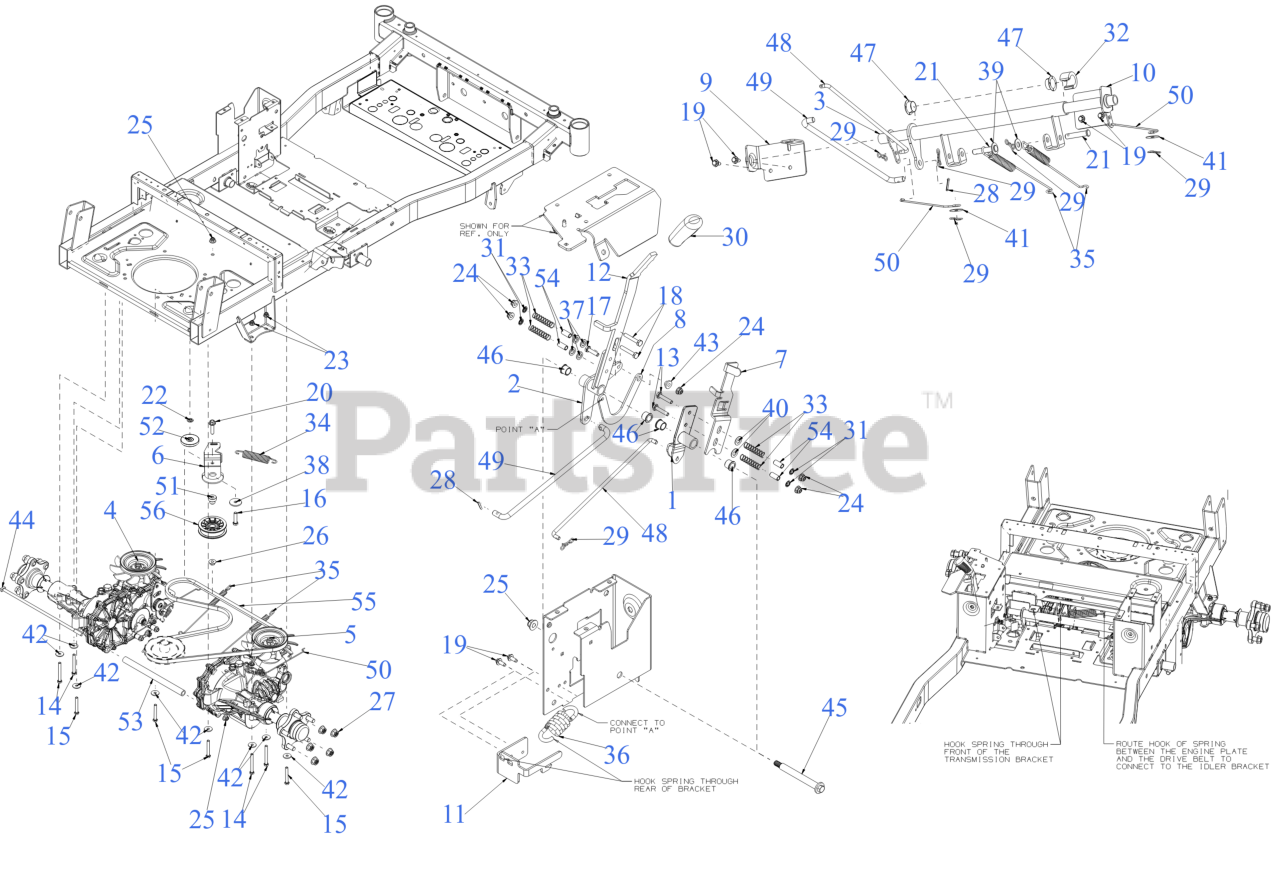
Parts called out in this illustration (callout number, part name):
1	BYPASS LEVER PIVOT ARM
2	PARK BRAKE PIVOT ARM
3	BRAKE PIVOT SHAFT
4	HYDRO TRANSMISSION (LH)
5	HYDRO TRANSMISSION (RH)
6	HYDRO DRIVE IDLER BRACKET
7	TRANSMISSION BYPASS LEVER
8	OVER CENTER LINK
9	BRAKE SHAFT SUPPORT (RH)
10	BRAKE SHAFT SUPPORT (LH)
11	SPRING MOUNTING BRACKET
12	PARK BRAKE LEVER
13	HEX SCREW 1/4-20 x 1.25
14	HEX SCREW 5/16-18 x 2.75
15	HEX SCREW 5/16-18 x 2.25 GR5
16	SCREW 3/8-16 x 1.50
17	SCREW 1/4-20 X1.00 GR5
18	SCREW 1/4-20 x 1.50 GR.5
19	SCREW M6-1 x .625
20	HEX HEAD BOLT (3/8-16:1.50 GR8)
21	CLEVIS PIN 3/8 x 1.87
23	FLANGE LOCK NUT 5/16-18
24	FLANGE LOCK NUT
26	FLANGE LOCK NUT
27	HEX FLANGE NUT 1/2-20 GR8
28	COTTER PIN
29	BOW TIE COTTER PIN 1/4-5/16
31	RETAINER-BOLT .25ID x .50OD
32	SPACER: .76ID x .75
33	COMPRESSION SPRING
34	EXTENSION SPRING .925 x 5.37
35	EXTENSION SPRING .60 DIAx9.09
36	EXTENSION SPRING 1.09x3.25
37	FLAT WASHER
38	FLAT WASHER .390x1.500x.134
39	FLAT WASHER
40	WASHER THRUST .375X.70X.030
41	FLAT WASHER
42	FLAT WASHER 1.0 OD:.331 ID
43	SHOULDER SPACER
44	SUPPORT TUBE ROD
45	SHOULDER SCREW .491x3.937 3/8-16
46	FLANGE BUSHING
47	FLANGE BEARING .75 x 1.125 x .375
48	BYPASS LINK
49	BRAKE LINK
50	HYDRO BYPASS ROD .100 DIA
51	SHOULDER SPACER
52	SHOULDER SPACER
53	SUPPORT TUBE
54	SPACER .252x.350x.760
55	TRANSMISSION DRIVE BELT A x 67
56	FLAT IDLER PULLEY 3.00 OD
